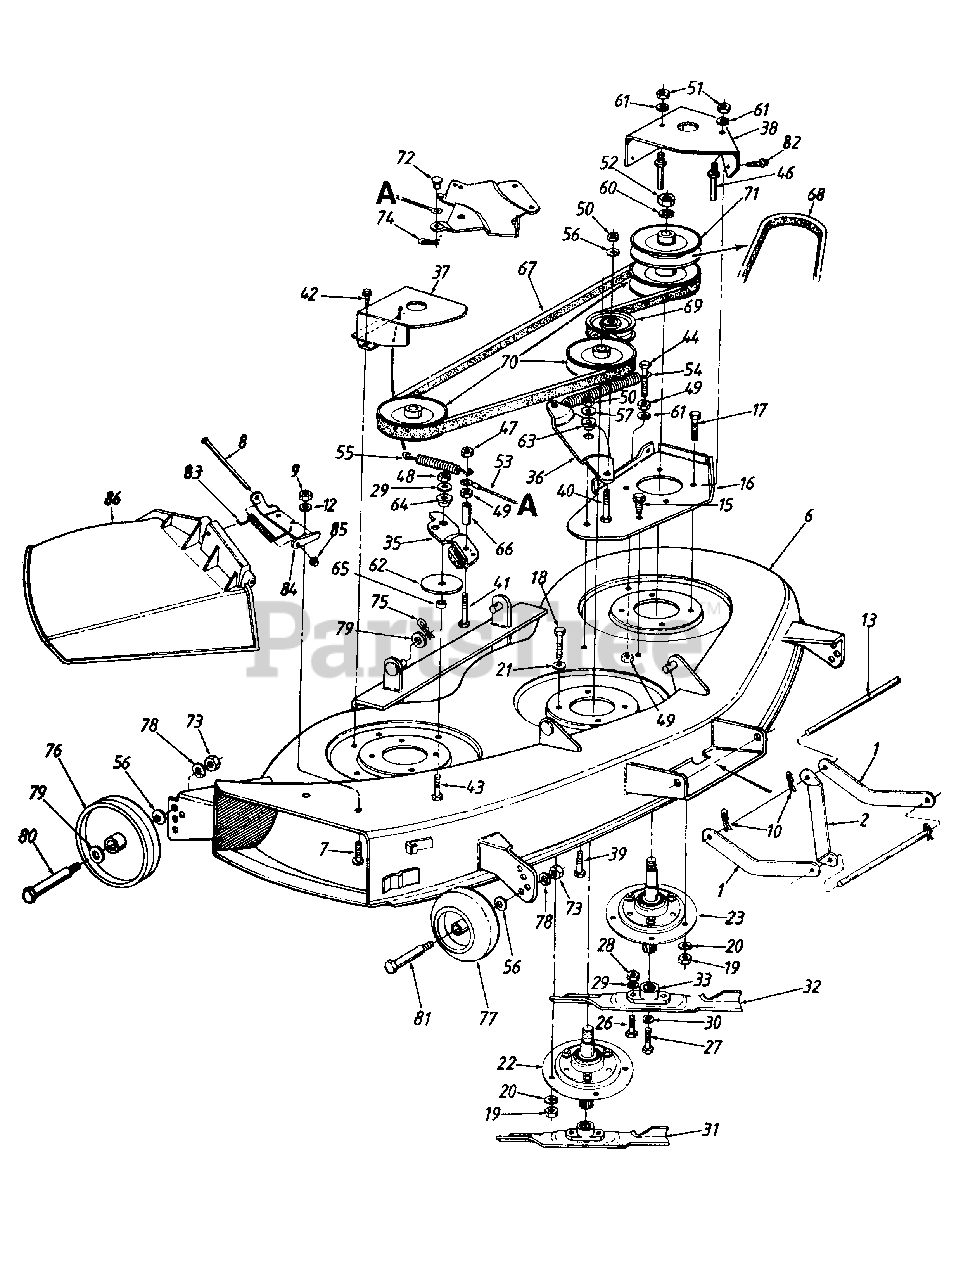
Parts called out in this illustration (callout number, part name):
7	Truss Mach. Scr. 1/4-20 x .75"
8	Hinge Pin
9	Hex Jam Nut 1/4-20 Thd.
10	Int. Cotter Pin
12	Bell-Wash. 1/4" I.D.
13	Deck Connecting Rod
15	Hex TT-Tap Scr. 5/16-18 x .62"
18	Hex Bolt 5/16-24 x .75" Lg.
19	Hex Nut 5/16-24 Thd.
20	L-Wash. 5/16" I.D.
21	Bell-Wash. 5/16" I.D.
22	Spindle Ass'y.
23	Spindle Ass'y.
26	Hex Bolt 5/16-24 x 1.0" Lg.
27	Hex Cl-Bolt 3/8-24 x .88" Lg.
28	Hex Nut 5/16-24 Thd.
29	L-Wash. 5/16" I.D.
30	L-Wash. 3/8" I.D. H.D.
31	High Lift Blade 14.88" Lg.
32	High Lift Blade 16.28n Lg.
33	Blade Adapter
35	Deck Brake Brkt. Ass'y.
36	Idler Bracket
40	Hex Bolt 3/8-24 x 1.5" Lg.
41	Hex Bolt 1/4-28 x 1.75" Lg.
42	Hex Wash. Hd. Tap-Scr. 1/4-20 x .5" Lg.
43	Hex Bolt 5/16-24 x 1.25n Lg. (Grade 5)
44	Hex Bolt 1/4-28 x 1.5" Lg.
46	Belt Guard Pin 1/4" Dia.
47	Hex Cent. L-Nut 1/4-28 Thd.
48	Hex Nut 5/16-24 Thd.
49	Hex Nut 1/4-28 Thd.
50	Hex Nut 3/8-24 Thd.
51	Hex Nut 1/4-20 Thd.
52	Hex Jam Nut 5/8-18 Thd.
53	Brake Cable Ass'y.
54	Extension Spring 6.17" Lg.
55	Extension Spring 3.97" Lg.
56	Bell-Wash. .38" I.D. x .88n O.D.
57	Bell-Wash. .39" I.D. x 1.13" O.D.
60	Bell-Wash. 5/8" I.D. x 1.25n O.D.
61	L-Wash. 1/4n I.D.
62	Fl-Wash. 5/16" I.D. x 3n O.D.
63	Shld. Spacer .625n I.D.
64	Shld. Spacer
65	Spacer.34" I.D.
66	Spacer.326" I.D.
67	V-Belt
68	V-Belt
69	Fl-ldler w/Flanges 3 5n O.D.
70	Pulley 5 on Dia.
71	Pulley 5.0" Dia.
72	Clevis Pin 1/4" Dia. x 53n Lg.
73	Hex Nut 3/8-16 Thd.
74	Intern. Cotter Pin 5/16" Dia.
75	Intern. Cotter Pin 3/8 Dia.
76	Deck Wheel 5n Dia.
77	Deck Wheel w/lnsert 5n Dia.
78	L-Wash. 3/8" I.D.
79	Fl-Wash..531" 1.D.
80	Shoulder Bolt 498" Dia. x 1.64" Lg.
81	Shoulder Bolt
82	Hex Wash. Hd. Tap-Scr. 1/4-20 x 88n Lg.
83	Torsion Spring
84	Hinge Mtg. Brkt.
85	Push Nut
86	Chute Ass'y. Comp.
